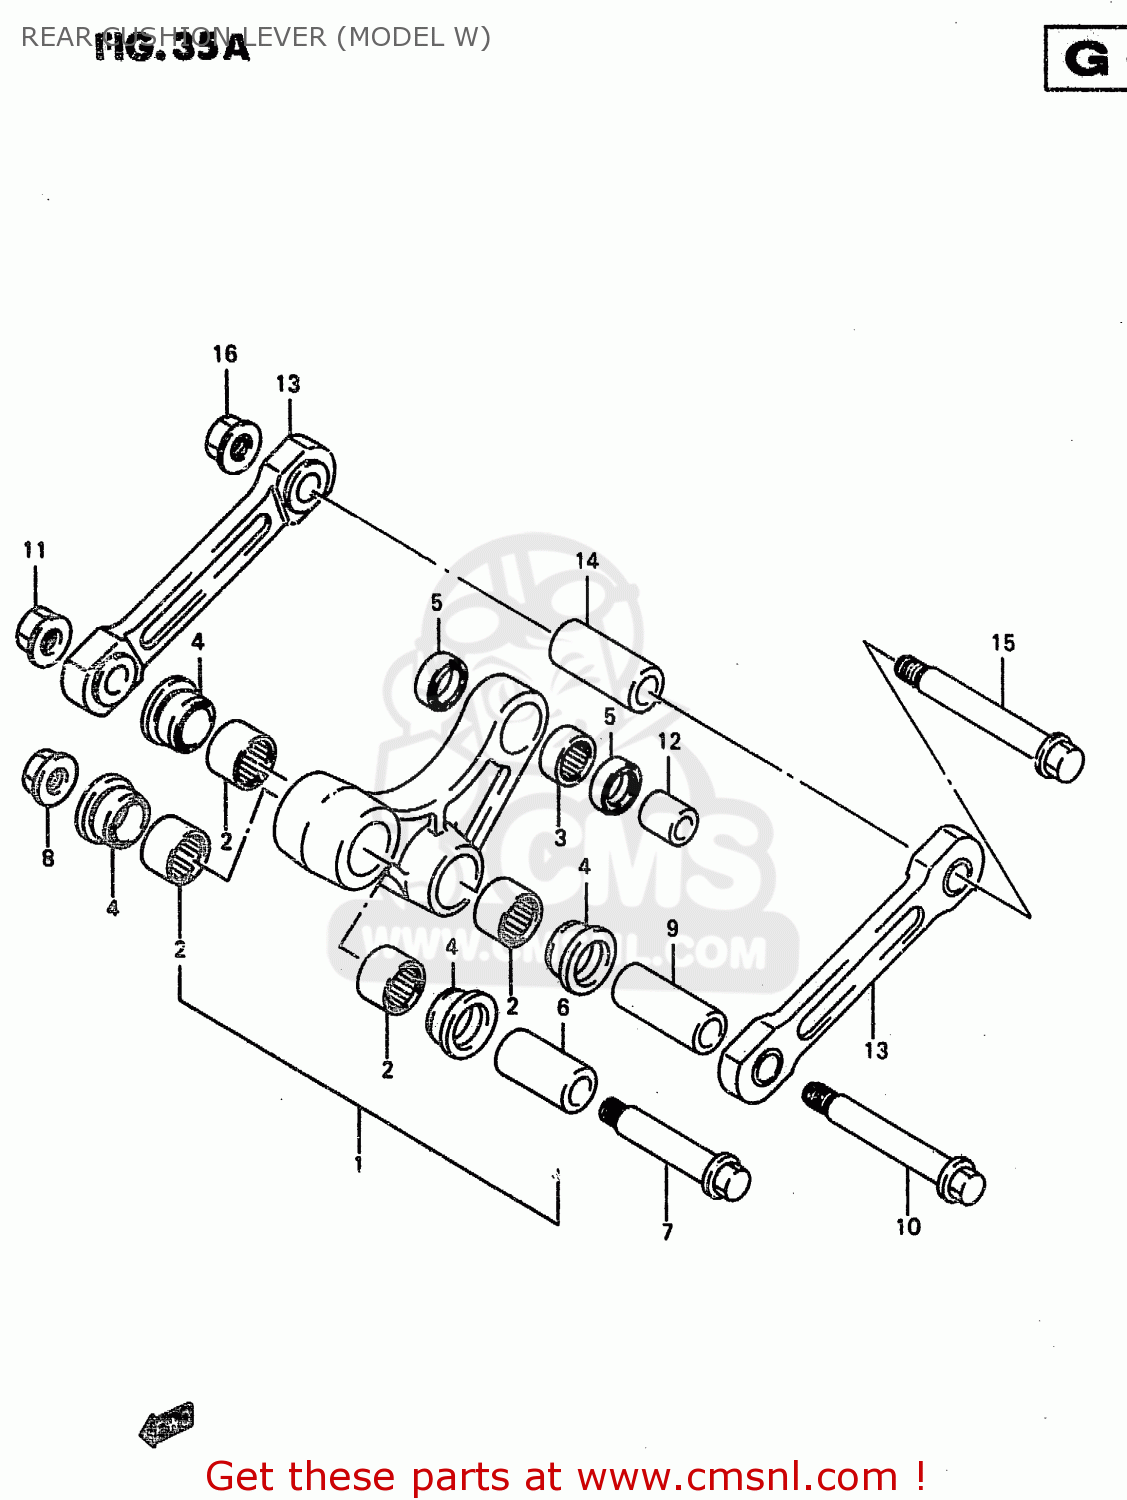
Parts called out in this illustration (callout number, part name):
1	LEVER SET,RR CUSHION
2	BEARING(22X28X16)
3	BEARING(20X26X12)
4	SEAL,SWINGING ARM RR
5	SEAL,OIL(20X26X4.5)
6	SPACER,RR CUSHION LEVER FR
7	BOLT,REAR CUSHION LEVER
8	NUT 12MM
9	SPACER,RR CUSHION
10	BOLT,REAR CUSHION
11	NUT 12MM
12	SPACER,RR CUSHION LEVER RR
13	ROD SET,REAR CUSHION
14	SPACER,RR CUSHION
15	BOLT,REAR CUSHION
16	NUT 12MM
